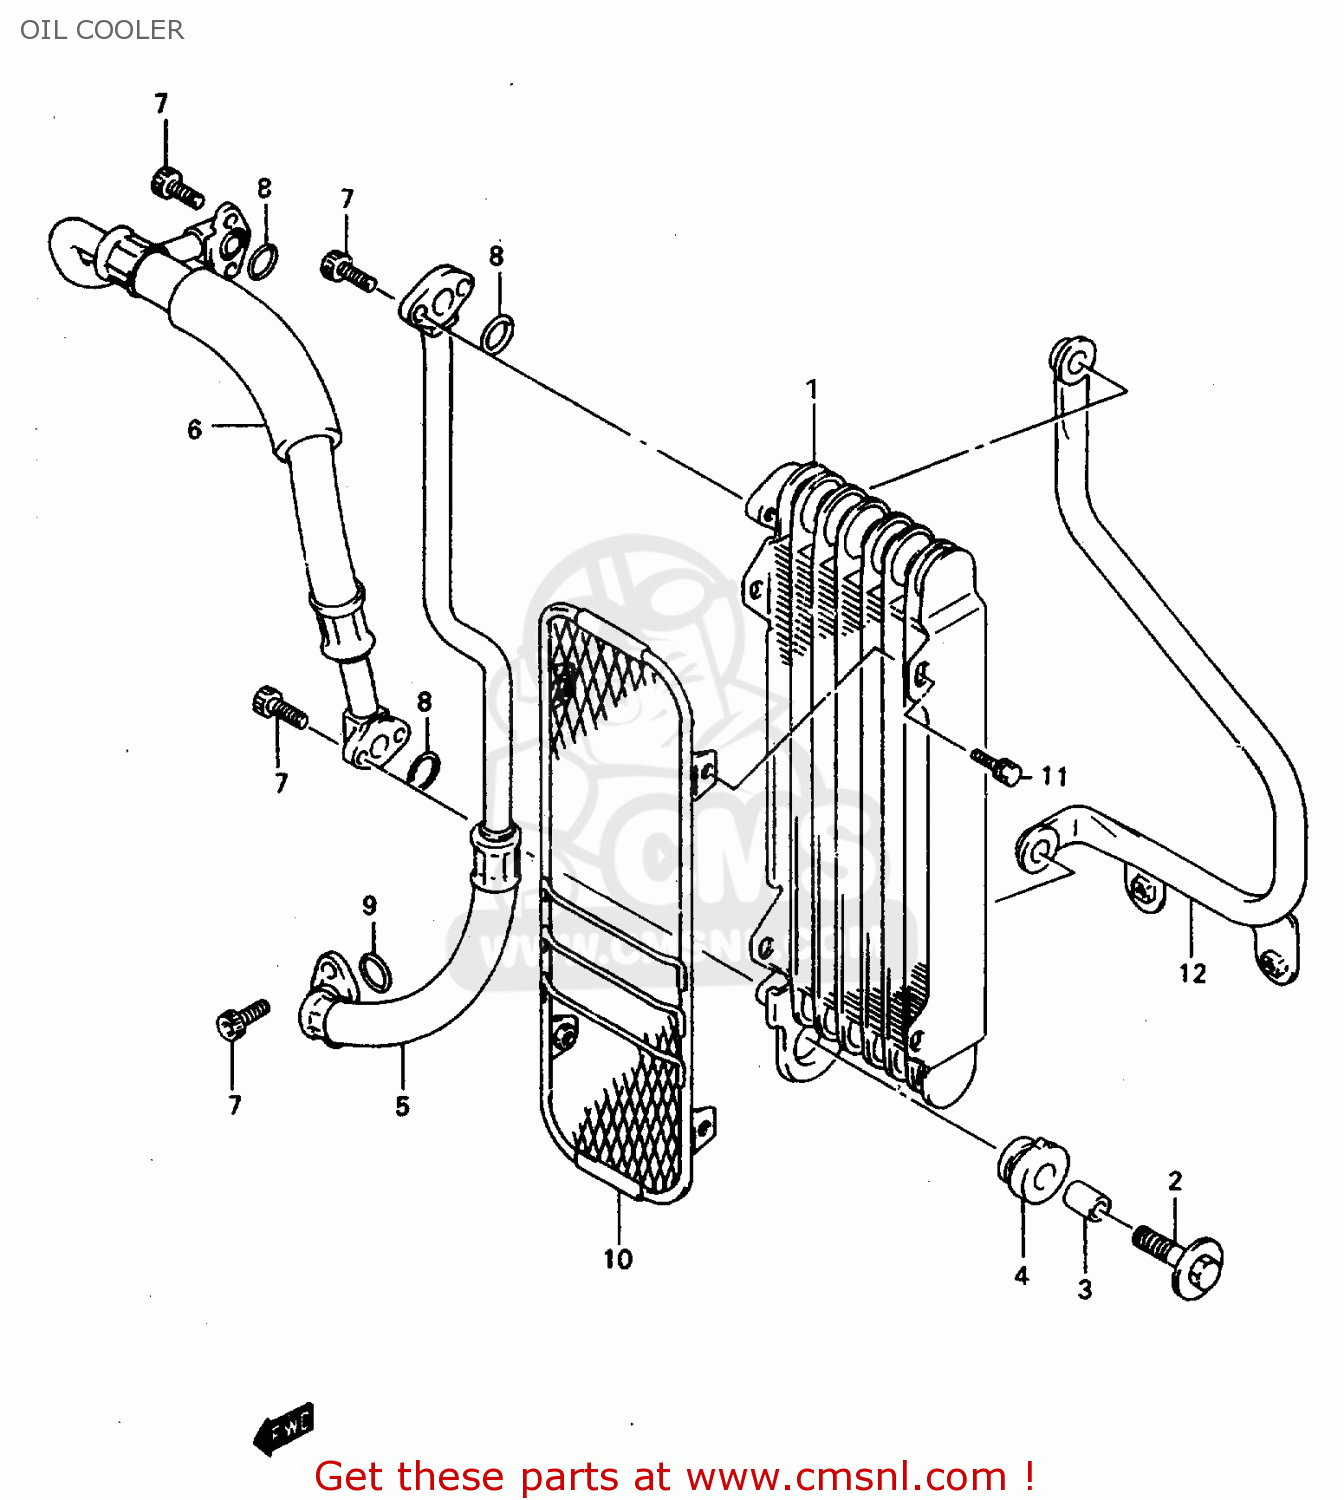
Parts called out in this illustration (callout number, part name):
1	COOLER ASSY,OIL
2	BOLT(8X45)
3	SPACER,OIL COOLER
4	CUSHION,OIL COOLER
5	HOSE,OIL COOLE
6	HOSE, OIL COOLER NO.2
7	BOLT,OIL FILLE
8	O RING(D:2.4,ID:12.3)
9	O RING,HEAD GASKET
10	BUMPER,OIL COOLER
11	BOLT
12	GUARD, OIL COOLER
